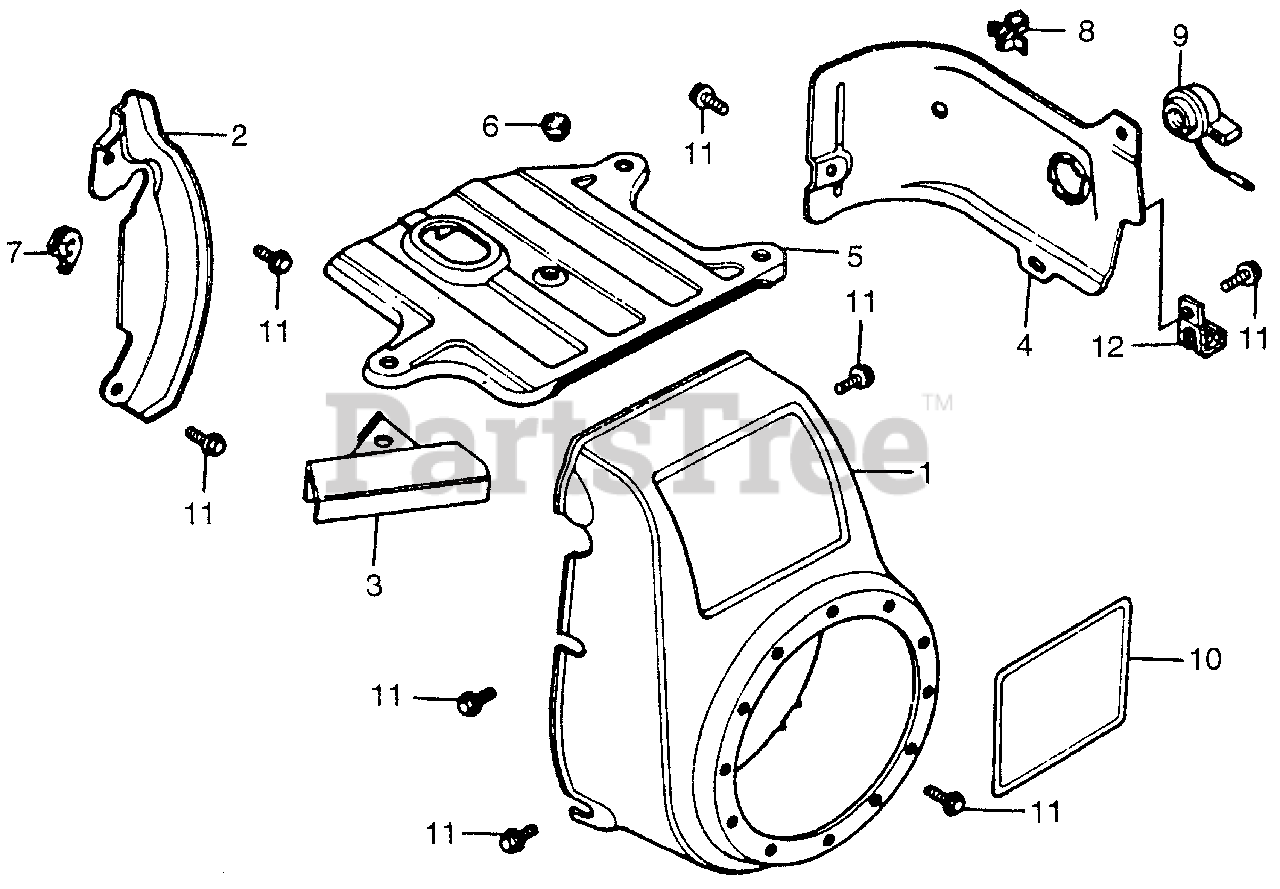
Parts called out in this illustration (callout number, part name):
1	COVER, FAN *R8* (BRIGHT RED)
2	PLATE, SIDE
3	GUIDE, AIR
5	COVER, TOP
6	GROMMET, TOP COVER
7	GROMMET, WIRE
8	CLIP, IGNITION WIRE (8MM)
9	SWITCH ASSY., ENGINE STOP
11	BOLT, FLANGE (6X12) (CT200)
12	CLIP, CABLE
